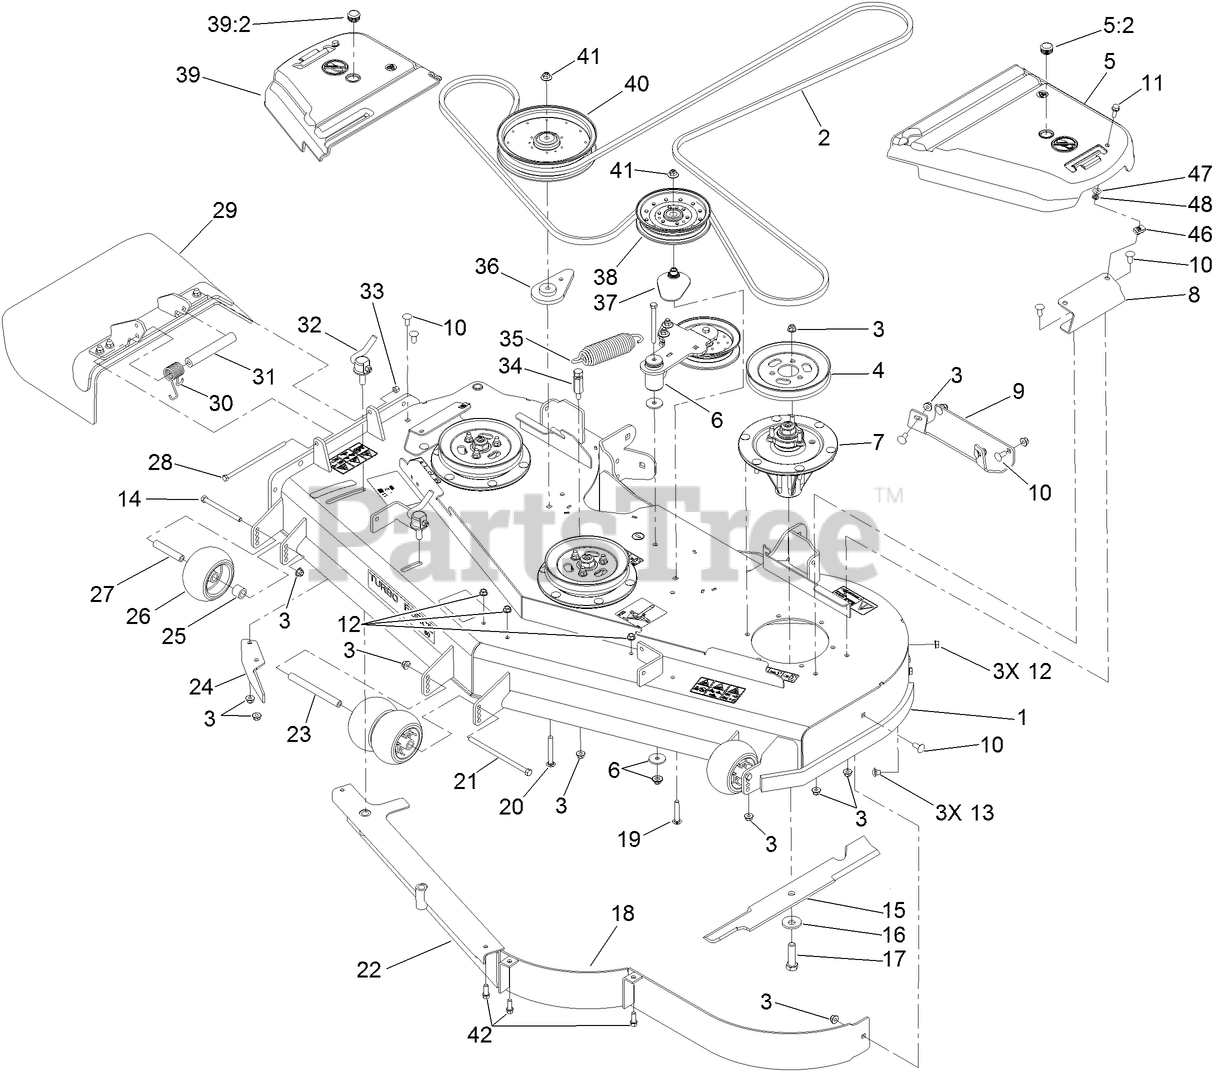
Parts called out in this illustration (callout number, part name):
1	DECK DECAL ASM
2	BELT-V
3	NUT-HF, NI
4	Pulley
5	LH BELT COVER ASM
5:2	PLUG-PLASTIC
6	IDLER ARM ASM
7	SPINDLE ASM
8	BRACKET-COVER, BELT
9	Plate-Skid
10	SCREW-CARR
11	SCREW-HHF
12	NUT-HHF, WHIZ
13	SCREW-CARR
14	SCREW-HH
15	BLADE-HI FLOW
16	Washer-Blade Bolt, Heavy
17	SCREW-BLADE
19	BOLT-CARR, SHORT NECK
20	SCREW-CARR
21	SCREW-HH
23	SPACER-WHEEL
24	BAFFLE-DISCHARGE
25	TUBE-SPACER
26	ROLLER-SCALP, ANTI
27	TUBE-SPANNER
28	SCREW-HH
29	RUBBER DEFLECTOR ASM
30	SPRING-TORSION
31	SPACER
32	LEVER ASM
33	NUT-LOCK, NI
34	ANCHOR-SPRING, TALL
35	EXTENSION-SPRING
36	SPACER-IDLER
37	SPACER-PULLEY
38	PULLEY-IDLER, FLAT
39	RH BELT COVER ASM
39:2	PLUG-PLASTIC
40	PULLEY-IDLER
41	NUT-FLANGE, NI
42	SCREW-HWH
46	NUT-U
47	WASHER-THRUST
48	NUT-PUSH
